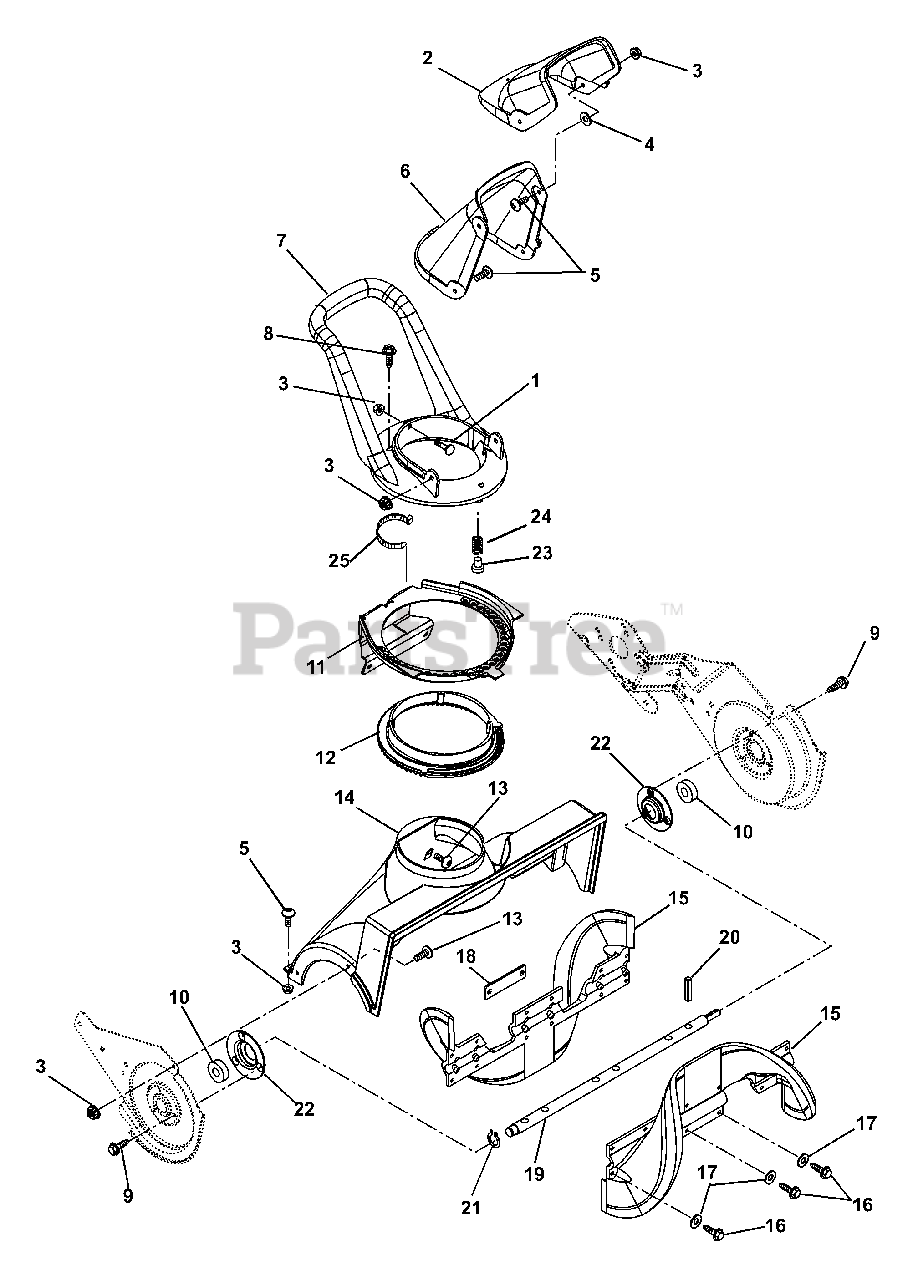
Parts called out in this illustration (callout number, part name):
1	@BLT-RDHDSQNK .25-20X.75 G5YZ
2	DEFLECTOR-DISCHARGE CHUTE ASSY
3	NUT-LK-FLG .250-20 PL BLK
4	WSHR-FL-RBR .31X1.25X.06
5	SCR-MCH .25-20X.75 TXTR YWZC
6	CHUTE-DISCHARGE ASSY
8	SCR TAP 8-18X1.50 SL HWH PL B
9	@SCR-TAP .25-20X.50 HWH TR YWZ
10	BRG-BALL .669X1.575X.47 (6203)
11	BRKT-DISCHARGE CHUTE ROTATION
12	GEAR-DISCHARGE CHUTE SEGMENT
13	SCR-MCH .25-20X.50 TXTR PL
14	HOUSING-IMPELLER ASSY
15	IMPELLER HALF
16	@SCR-TAP .25-20X1.00 HWH TR YZ
17	WSHR-FL-STL .281X1.000X.063
18	PLATE-BOLT,SELF-TAPPING
19	SHAFT-IMPELLER
20	PIN-ROLL .250X1.75 ZINC PL
21	RG-RTNG-EXT .672X.035
22	CUP-BRG
23	RVT- .250 X 1.125 TRUSS YWZC
24	SG-COMP .045X.360X1.75 WLD12.5
25	CABLE TIE LG 5-1/2
